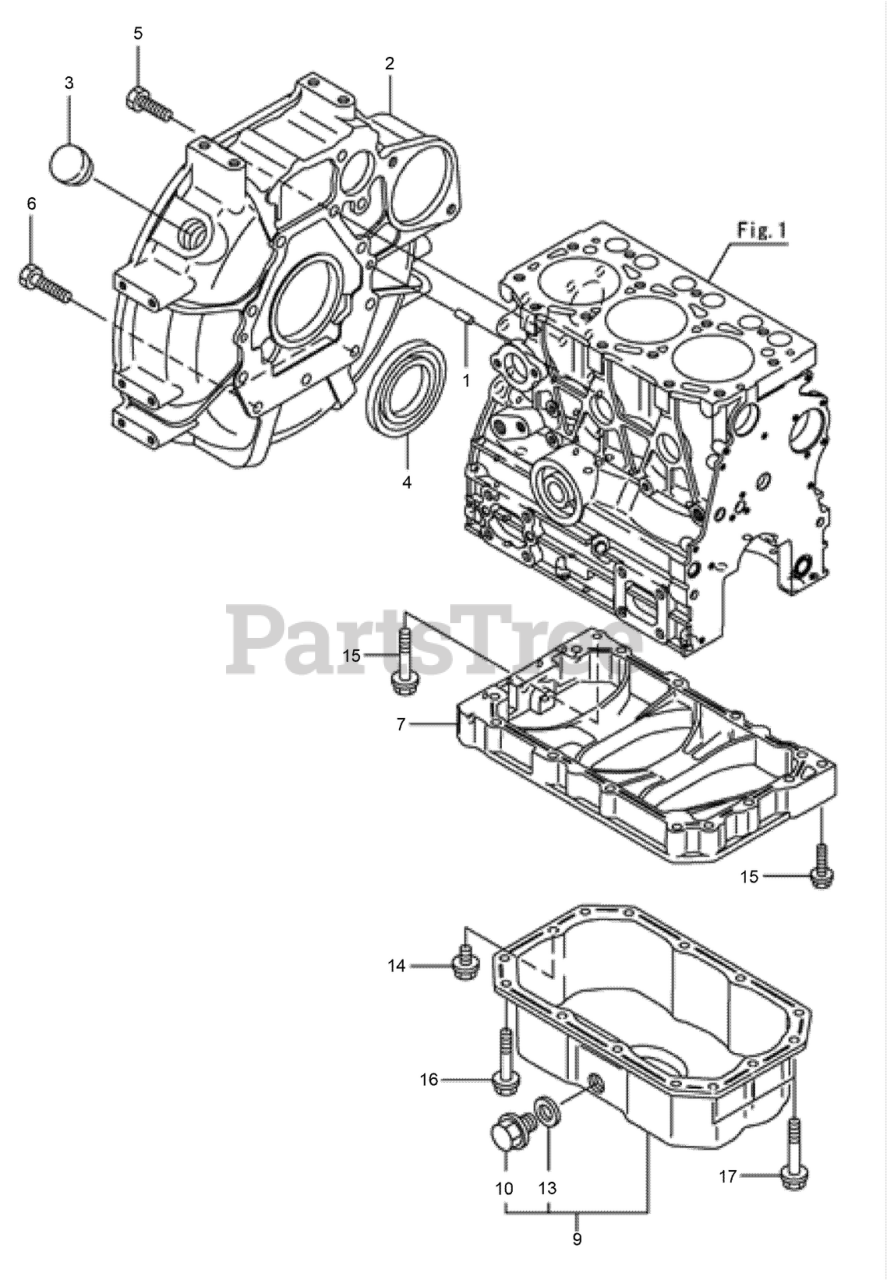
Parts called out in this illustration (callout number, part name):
2	HOUSING-FLYWHEEL
4	SEAL-OIL
7	SPACER-OIL PAN
9	OIL PAN ASM
13	WASHER-SEAL
